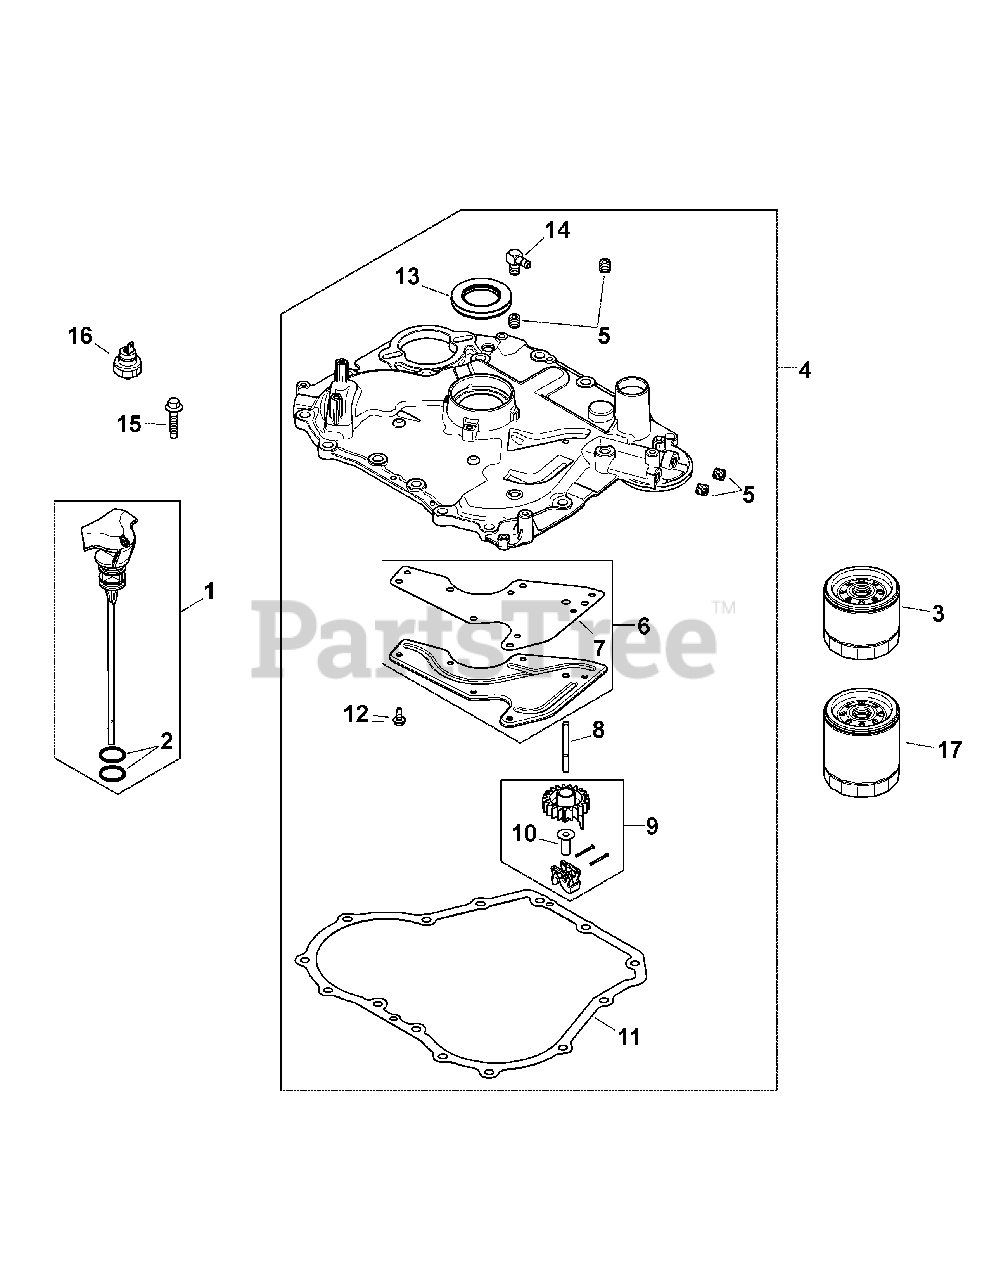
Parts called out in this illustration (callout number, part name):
1	Dipstick Assembly-Std Yellow
2	O-Ring
4	Closure Plate Assembly
5	Ctsk Pipe Plug, 1/8
6	Oil Passage Cover Kit
7	Oil Passage Gasket
8	Governor Cross Shaft
9	Governor Gear Assembly
10	Governor Regulating Pin
11	Closure Plate Gasket
12	Flg. Thd. Frm. Screw, M5 X 0.8 X 13
13	Oil Seal
14	90° Hose Connector
15	Hex Flange Screw, 1/2
16	Fuse Block
17	Fuse Block
